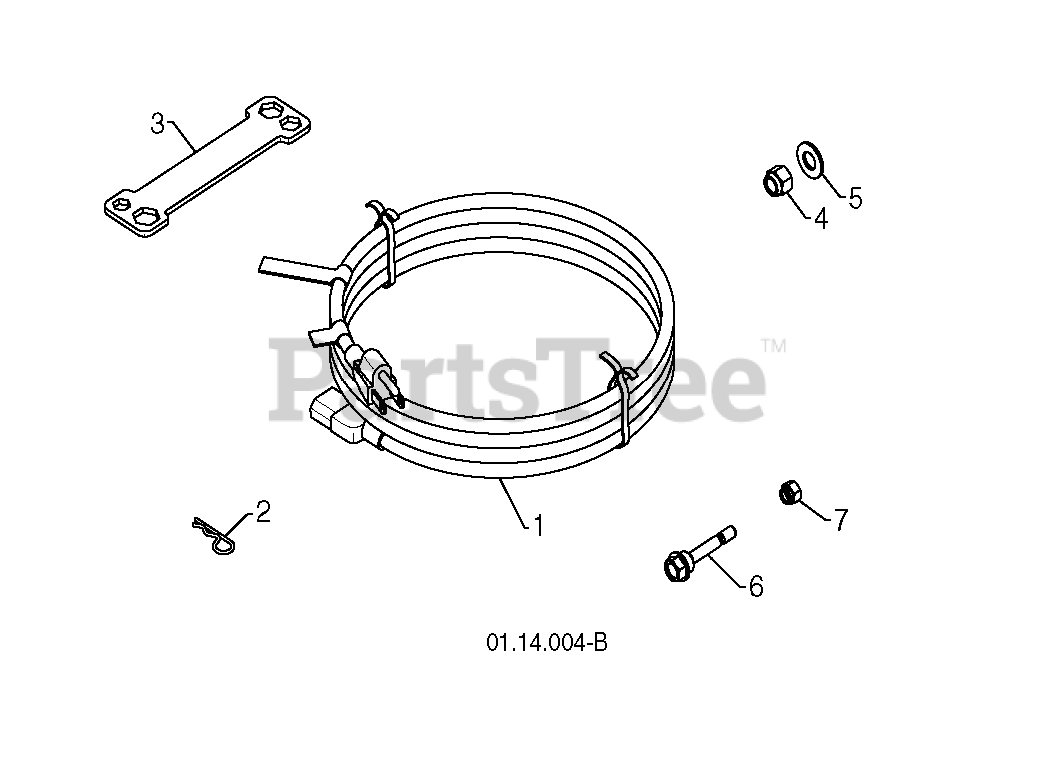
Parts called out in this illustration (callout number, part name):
1	CORD.ELECTRIC.10FT.120V.SNOW
2	SPRING RETAINER
3	WRENCH.SNOWTHROWER.ZINC.YZ
4	NUT
5	WASHER
6	BOLT.SHOULDER.SHEAR.1/4-20.
7	LOCKNUT.NYLOC.1/4-20
